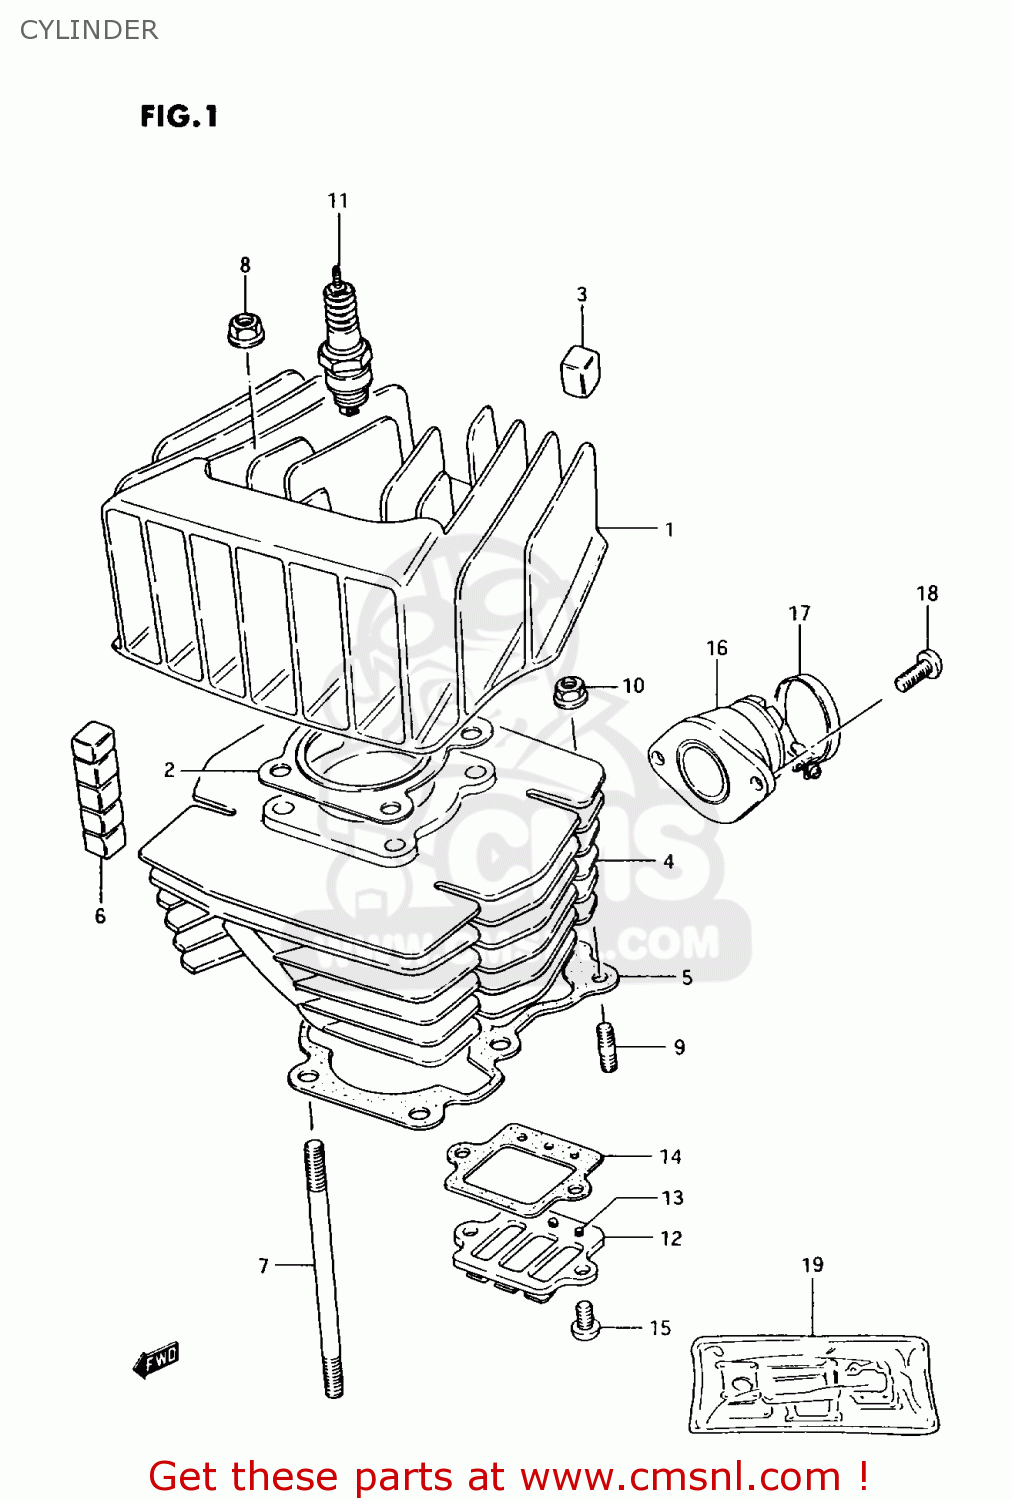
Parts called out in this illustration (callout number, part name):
1	HEAD,CYLINDER
2	GASKET,CYLINDER HEAD (NAS)
3	PAD,CYLINDER
4	CYLINDER
5	GASKET, CYLINDER (NAS)
6	PAD,CYLINDER
7	BOLT,STUD
8	NUT
9	STUD 6X16
10	NUT
11	PLUG,SPARK
12	VALVE ASSY,REED
13	SCREW
14	GASKET,REED VALVE (NAS)
15	SCREW
16	PIPE,INTAKE
17	CLAMP
18	SCREW
19	GASKET SET (NAS)
